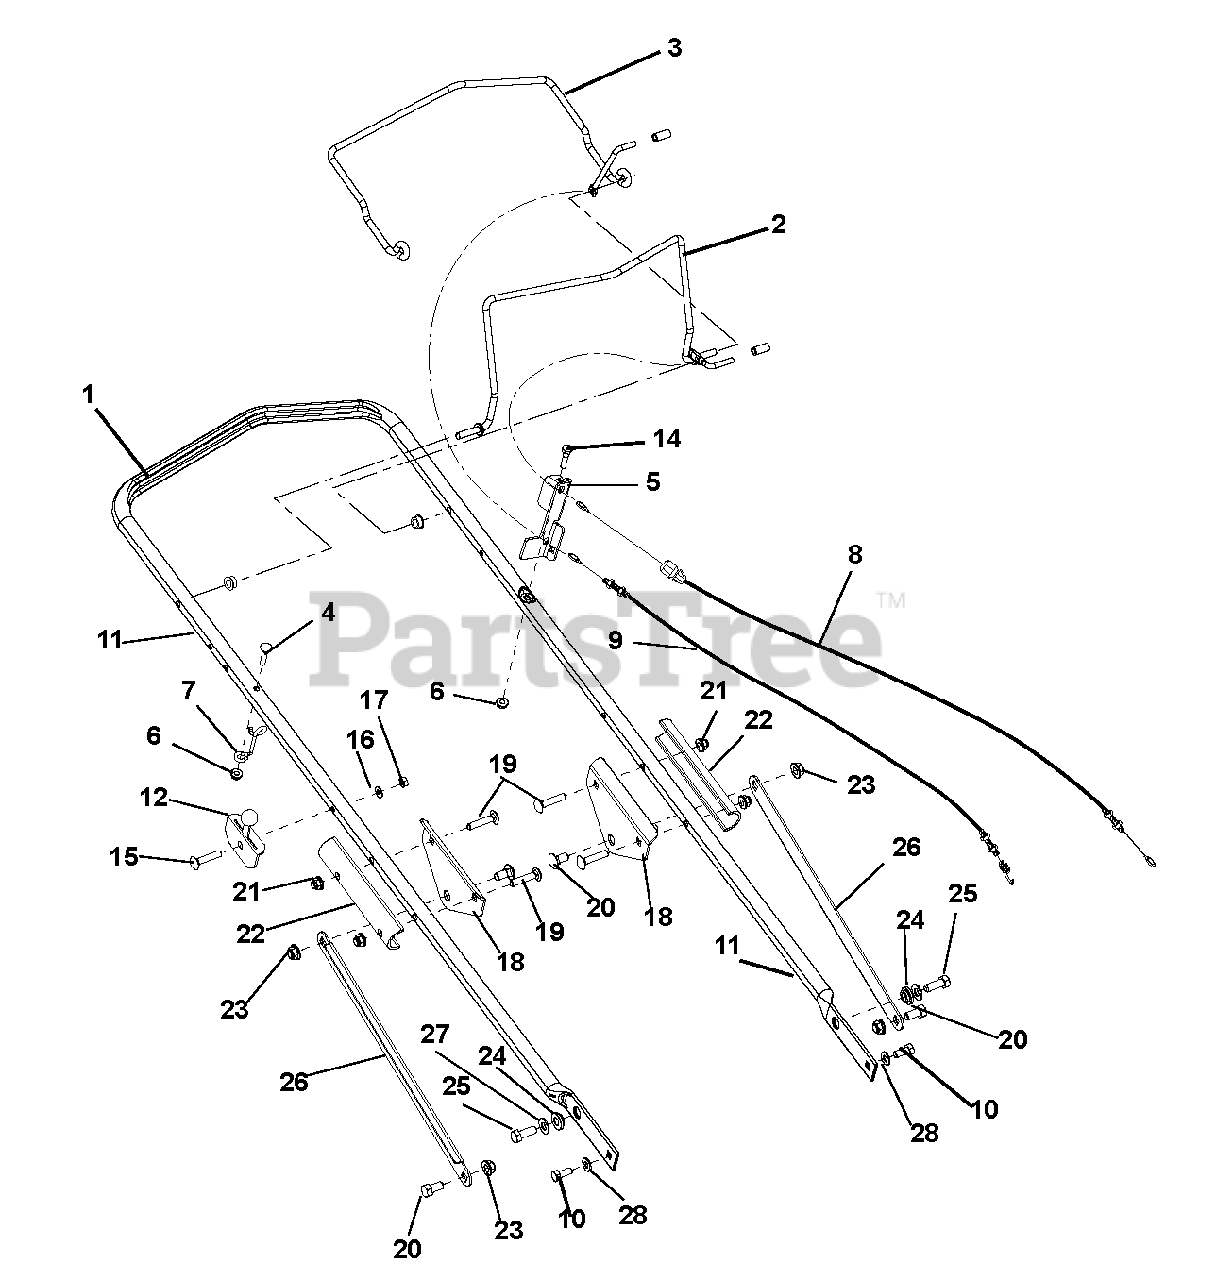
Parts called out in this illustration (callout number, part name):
1	Handlebar
2	Bail, Operator Presence
3	Bail, Clutch
4	Bolt, Round Head Square Neck .25-20 x 1.25
5	Anchor, Cable Thumb Adjustment
6	Nut-Locking-Top-Flange .25-20
7	Guide, Pullcord
8	Cable, Operator Presence Control (911251, 255)
9	Cable, XD Double Bail Drive
10	Bolt, Hex .31-18 x .75 Grade 5
11	Clip, Conduit (911253)
12	Throttle Control, Honda (911251, 255)
13	Plate, Hinge
14	Bolt, Hex .25-20 x 1.25 Grade 5
15	Bolt, Round Head Square Neck .25-20 x 1.75 Grade 5
16	Washer, Flat-Steel .25 x .562 x .049
17	Nut, Locking-Center .25-20
18	Plate, Handlebar
19	Bolt, Round Head Square Neck .31-18 x 1.50 Grade 5
20	Bolt, Hex .38-16 x .75 Grade 5
21	Nut, .31-18 Nyloc Flange
22	Service Bar Brace
23	Nut, .38-16 Nyloc Flange
24	Bushing, Flange .406 x .88 x .270 x .140
25	Bolt, Hex .38-16 x 1.00 Grade 5
26	Strap, Handlebar
27	Washer, Flat-Steel .406 x .812 x .065
28	Washer, Flat-Steel .344 x .688 x .065
